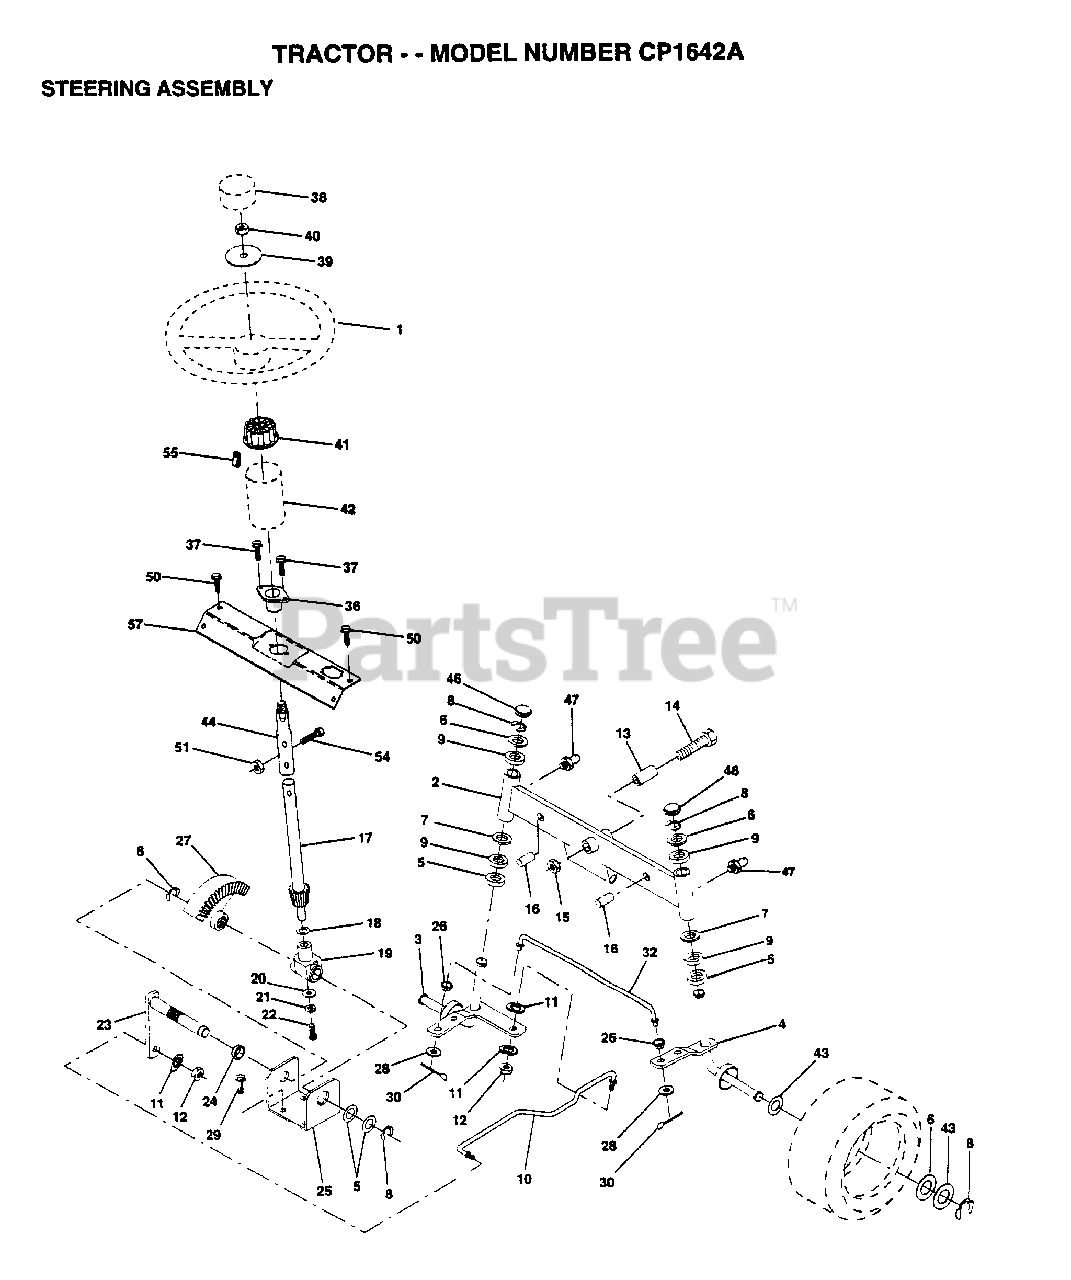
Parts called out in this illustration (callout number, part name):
2	AXLE ASM FRONT
3	SPINDLE LH
4	SPINDLE RH
5	WASHER .T
6	WASHER
7	WASHER
8	RING
9	COL. SRTG. BEAR.
11	LOCKWASHER
13	BEARING
14	BOLT HEX 5/8-11
15	"NUT-LOC,FLANGE LT"
16	AXLE PIN
17	SHAFT ASM STEERIN
18	THRUST WASHER
19	SUPPORT.SHAFT
21	LOCKWASHER
22	"SCREW,SPECIAL"
24	NYLINER T
25	"BRKT,STEERING"
26	BUSHING.DRAGLINK
27	GEAR SECTOR
28	WASHER
29	SCREW
30	COTTER PIN
32	TIE ROD
38	ST WHL INSERT CAP
39	WASHER T
40	GRIPCO NUT
41	ADAPTER-WHEEL LT
42	BOOT SHAFT STEER
43	WASHER
44	SHAFT EXT STEER
46	PUMP.2003081.
47	ZERK M
50	SCREW HEX CRT
51	NUT
54	BOLT
55	CLIP TINNERMAN
57	SUPPORT SHAFT STR
